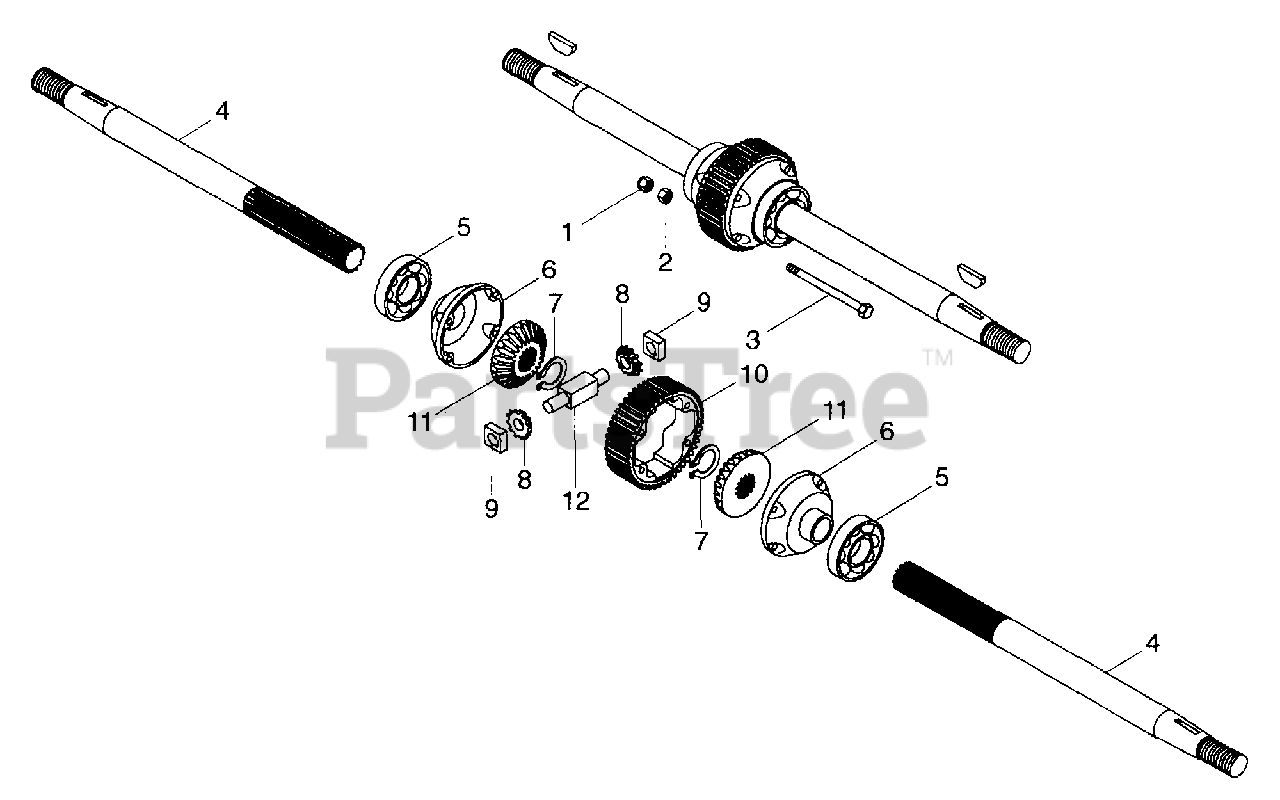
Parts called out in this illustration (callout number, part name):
1	Nut-Locking-Nylon .312-18 Grade 2
2	Nut-Hex .312-18 Grade 8
3	Bolt-Hex .31-18 x 2.75 Grade 8
4	Axle, Bevel Gear Differential
5	Bearing-Ball 1.57 x 2.68 x .59
6	Cap, Differential End
7	Ring-Retaining-External 1.150 x .093
8	Pin. Bevel
9	Block, Drive
10	Gear, Final Drive
11	Gear, Bevel
12	Pin, Spider Pinion
